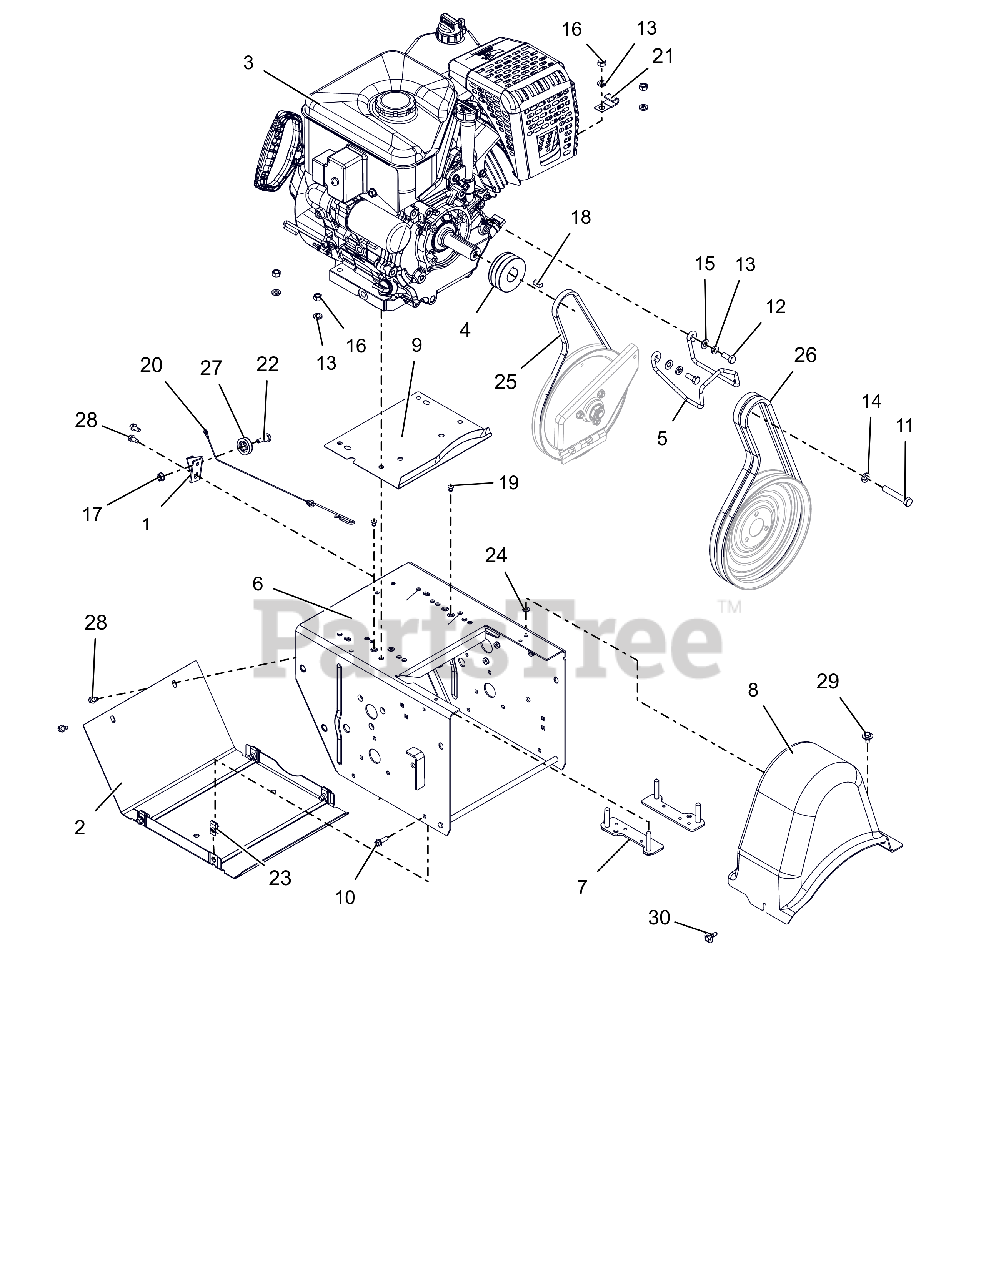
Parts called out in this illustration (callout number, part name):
1	BRACKET, CABLE PULLEY
2	COVER, BOTTOM
3	ENGINE, AX369 GEN 3 120V/60W
4	SHEAVE, DRIVE
5	FINGER, BELT
6	FRAME, MAIN-DELUXE(WELDMENT)
7	STRAP, BOLT-LARGE
8	COVER, BELT-LARGE
9	BAFFLE, WATER - LARGE BLOCK
10	BLT-HEX .25-20X.75 HWH YZ GR5
11	BLT-HEX .38-24X2.25 YWZC GR5
12	BLT-HEX .31-24X.75 YWZC GR5
13	WSHR-LK .312X.097 HVY YWZC
14	@WSHR-LK .38X.094 REG YWZC
15	@WSHR-FL-STL.344X.688X.065YWZC
16	@NUT-HEX .31-18 YWZC
17	@NUT-LK-TOP-FLG .25-20 YWZC
18	KEY-SQ .25X.625X.25 SAE 8630
19	RVT-POP .187 YZ
20	CABLE, LOWER TRACTION,SS & PRO
21	J-CLAMP
22	BOLT, SHLDR-.375X.375X.25-20
23	NUT-RTNR .25-20X.56
24	NUT-PUSH .25X.50 O.D.
25	V-BELT, 3L-WRAPPED
26	V-BELT, HA-RAW EDGE (SET)
27	PULLEY, CABLE
28	SCR-TAP .25-20X.50 HWH TR YWZ
29	SCR-TAP .25-20X.50 LGHWH TR YZ
30	SCR-TAP .25-20X.5 CAPTIVE
